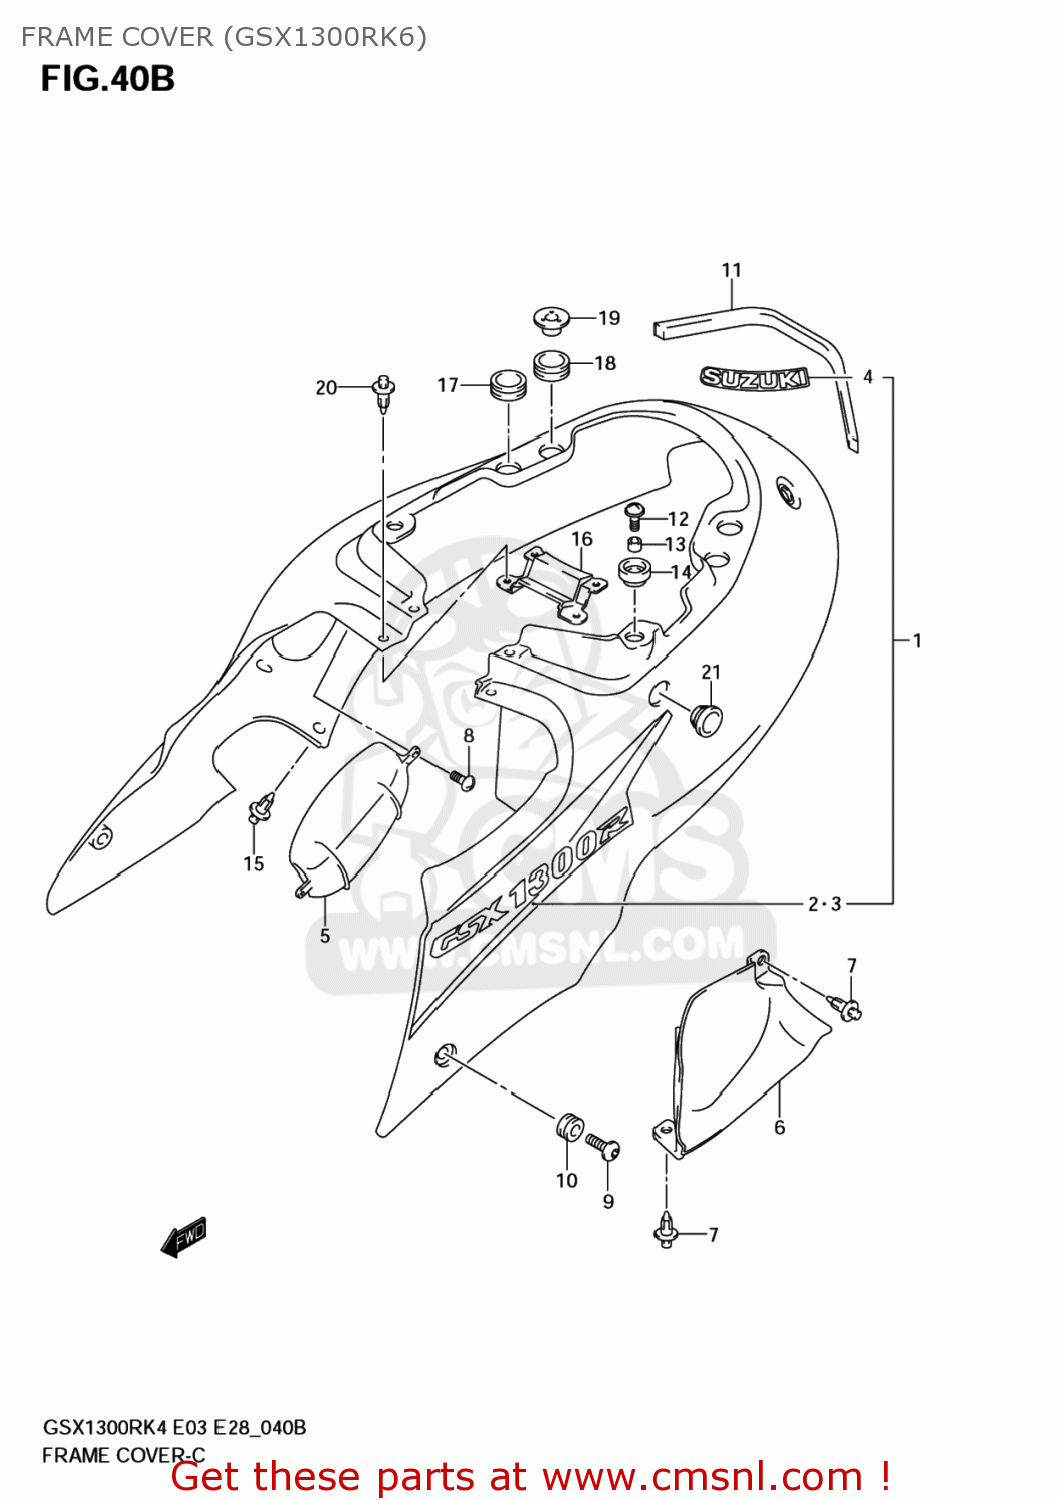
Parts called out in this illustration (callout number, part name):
1	COVER,FRAME(GRAY)
2	TAPE,FRAME COVER,R
3	TAPE,FRAME COVER,L
4	EMBLEM(GRAY)
5	CAP,FRAME COVER HOLE,R
6	CAP,FRAME COVER HOLE,L
7	CLIP(BLACK)
8	SCREW
9	SCREW(6X20)
10	CUSHION
11	CUSHION,FRAME COVER UPR
12	SCREW(6X20)
13	SPACER(6.5X10X11)
14	CUSHION
15	CLIP(BLACK)
16	COVER,FRAME CTR
17	CUSHION,FRAME COVER UPR RR
18	CUSHION,FRAME COVER UPR RR RR
19	WASHER,FRAME C
20	CLIP(BLACK)
21	CUSHION,FRAME COVER CTR
